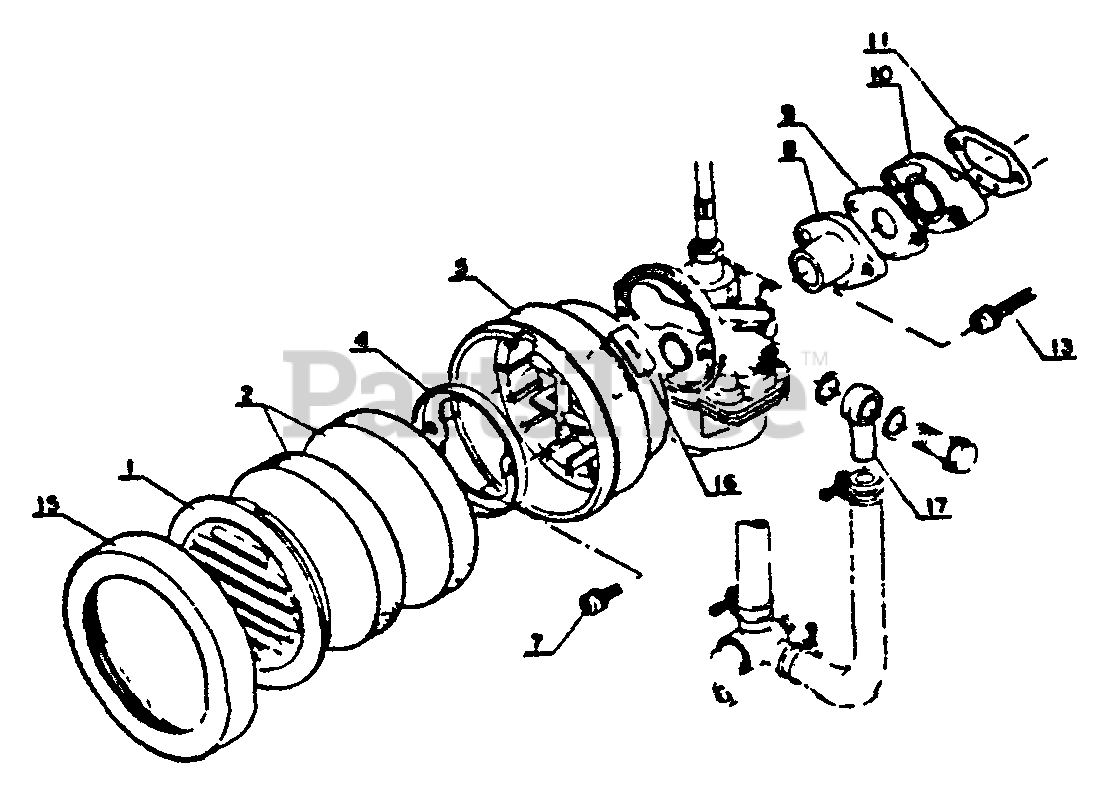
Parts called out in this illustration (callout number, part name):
1	COVER, AIR FILTER
2	FILTER, AIR
4	BRACKET, AIR FILTER
5	CASE, AIR FILTER
7	SCREW 4×10
8	ADAPTER, INTAKE
9	GASKET, INTAKE
10	INSULATOR, INTAKE
11	GASKET, INTAKE
13	SCREW 4×25
15	COVER, AIR FILTER
16	LABEL - CHOKE
17	CONNECTOR
